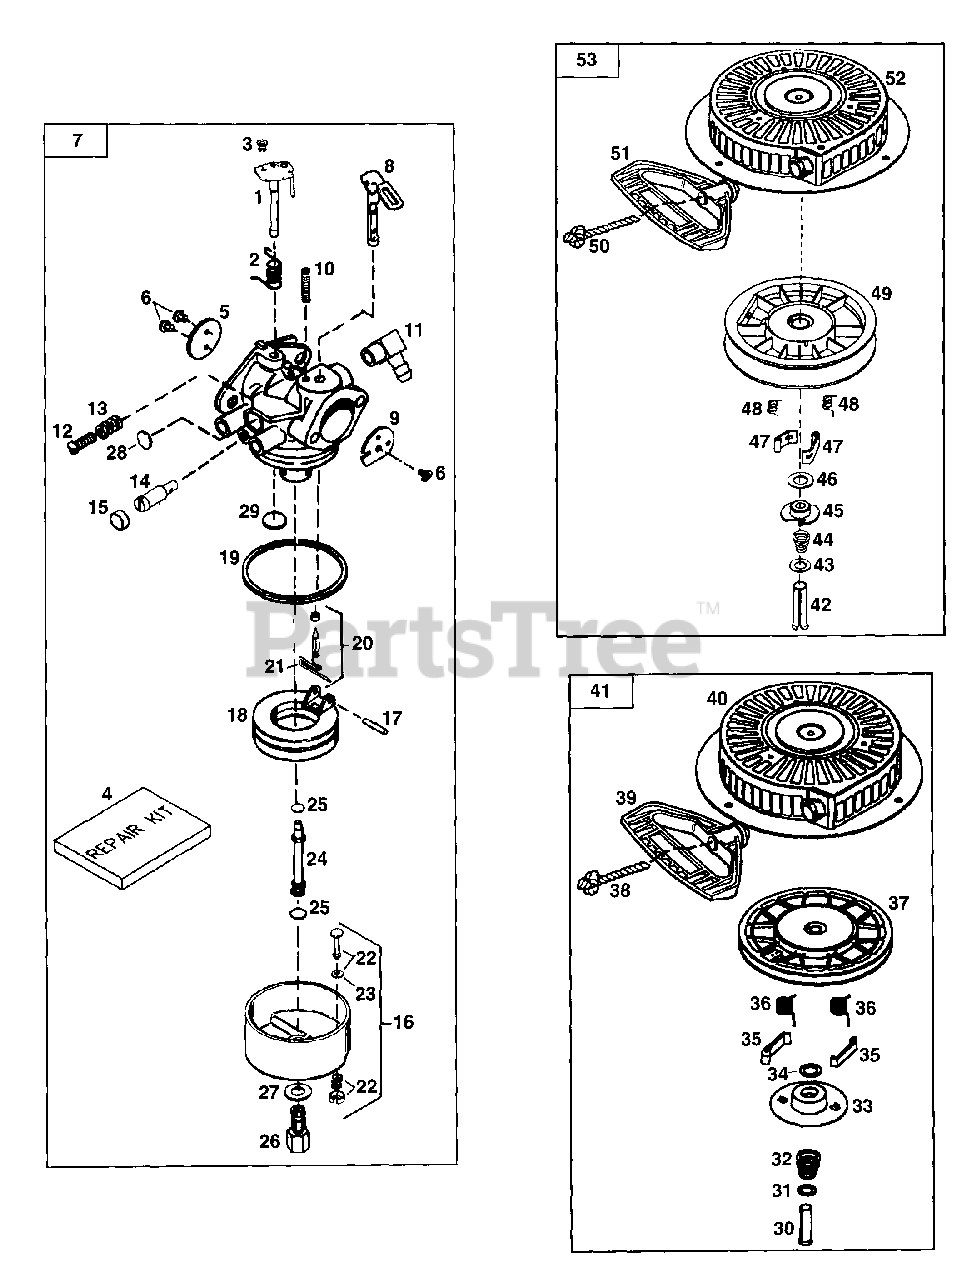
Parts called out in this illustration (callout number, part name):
1	Throttle Shaft & Lever Ass'y
2	Throttle Return Spring
4	Carburetor Repair Kit
5	Throttle Shutter
6	Shutter Screw
7	Carburetor Ass'y
8	Choke Shaft & Lever Ass'y
9	Choke Shutter
10	Choke Positioning Spring
11	Fuel Fitting
12	Throttle Crack/Idle Speed Screw
13	Tension Spring
14	Idle Restrictor Screw
15	Idle Restrictor Screw Cap
17	Float Shaft
18	Float
19	Float Bowl "O" Ring
20	Inlet Needle, Seat & Clip
21	Spring Clip
22	Bowl Drain Ass'y
23	Drain Plunger Gasket
24	Main Nozzle Tube
25	Main Nozzle Tube "O" Ring
26	High Speed Bowl Nut
27	Bowl Nut Washer
28	Welch Plug, Idle Mixture Well
29	Welch Plug, Atmospheric Vent
30	Spring Pin
32	Brake Spring
35	Starter Dog
36	Dog Spring
37	Pulley & Rewind Spring Ass'y
38	Starter Rope (98")
39	Mitten Grip Starter Handle
40	Starter Housing Ass'y
41	Rewind Starter Ass'y
42	Spring Pin,
44	Brake Spring
47	Starter Dog
48	Dog Spring
49	Pulley & Rewind Spring Ass'y
50	Starter Rope (98")
51	Mitten Grip Starter Handle
52	Starter Housing Ass'y
53	Rewind Starter Ass'y
